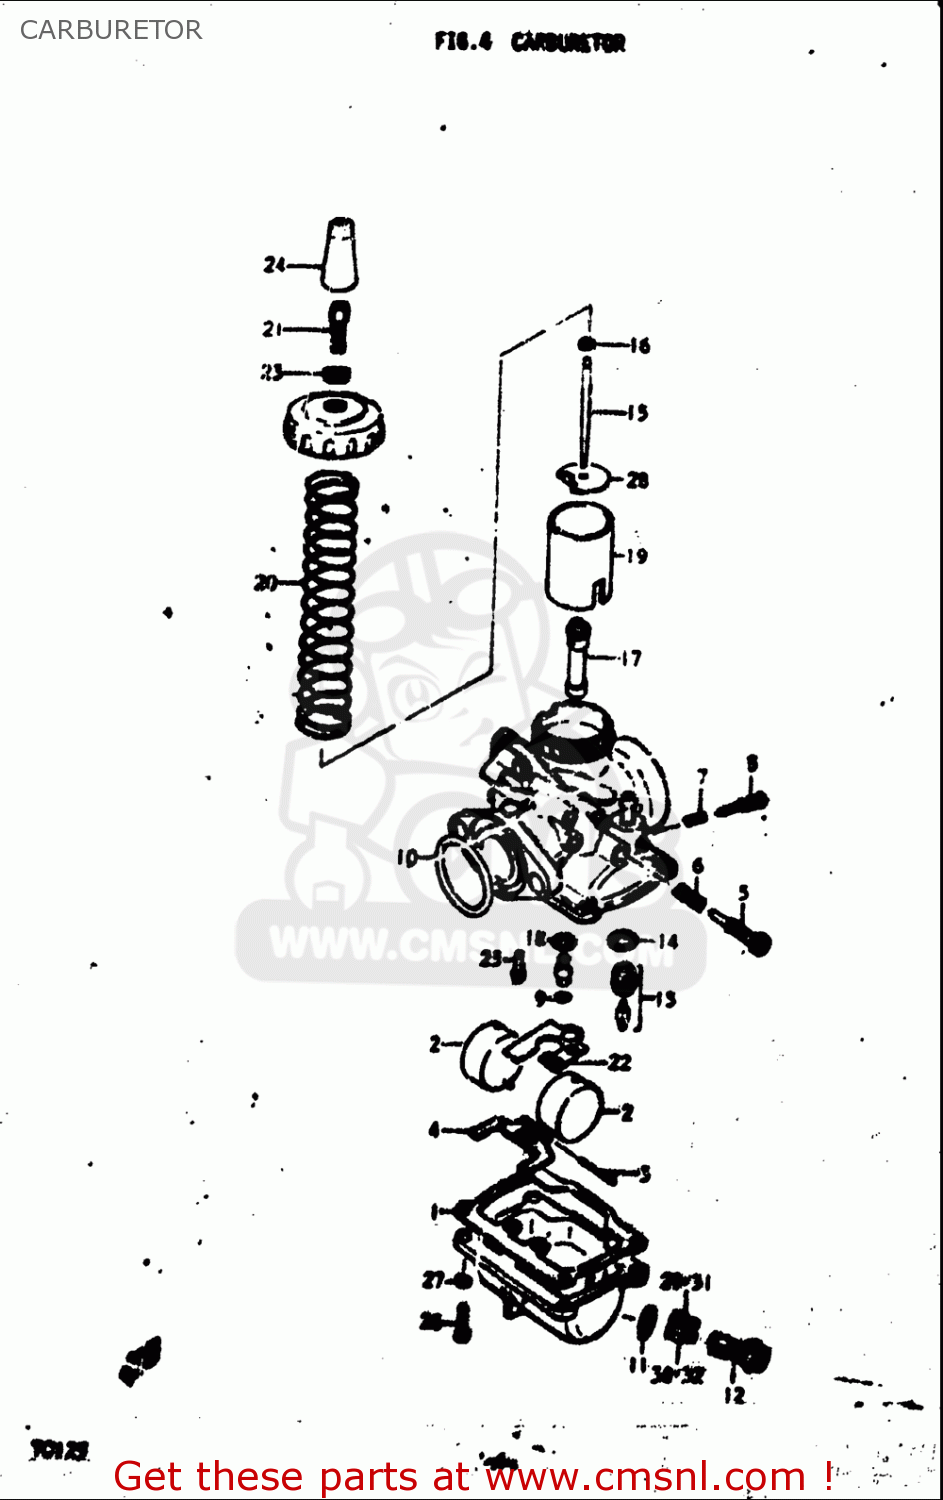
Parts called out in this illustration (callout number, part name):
1	GASKET,FLOAT CHAMBER (NAS)
2	FLOAT
5	SCREW,THROTTLE STOP
6	SPRING,THROTTLE SCREW
7	SPRING
8	SCREW,PILOT AIR
9	O RING
10	O RING
13	VALVE ASSY,NEEDLE
14	GASKET,VALVE SEAT (NAS)
15	NEEDLE,JET
16	CLIP
18	WASHER
20	SPRING,THROTTLE VALVE
21	ADJUSTER,CABLE
22	PLATE
23	NUT
24	CAP
25	JET,PILOT(25)
26	SCREW 4X16
27	WASHER,LOCK
28	SEAT,THROTTLE VALVE SPRING
29	JET,MAIN(90)
30	JET,MAIN(120)
31	JET,MAIN
32	JET,MAIN(125)
